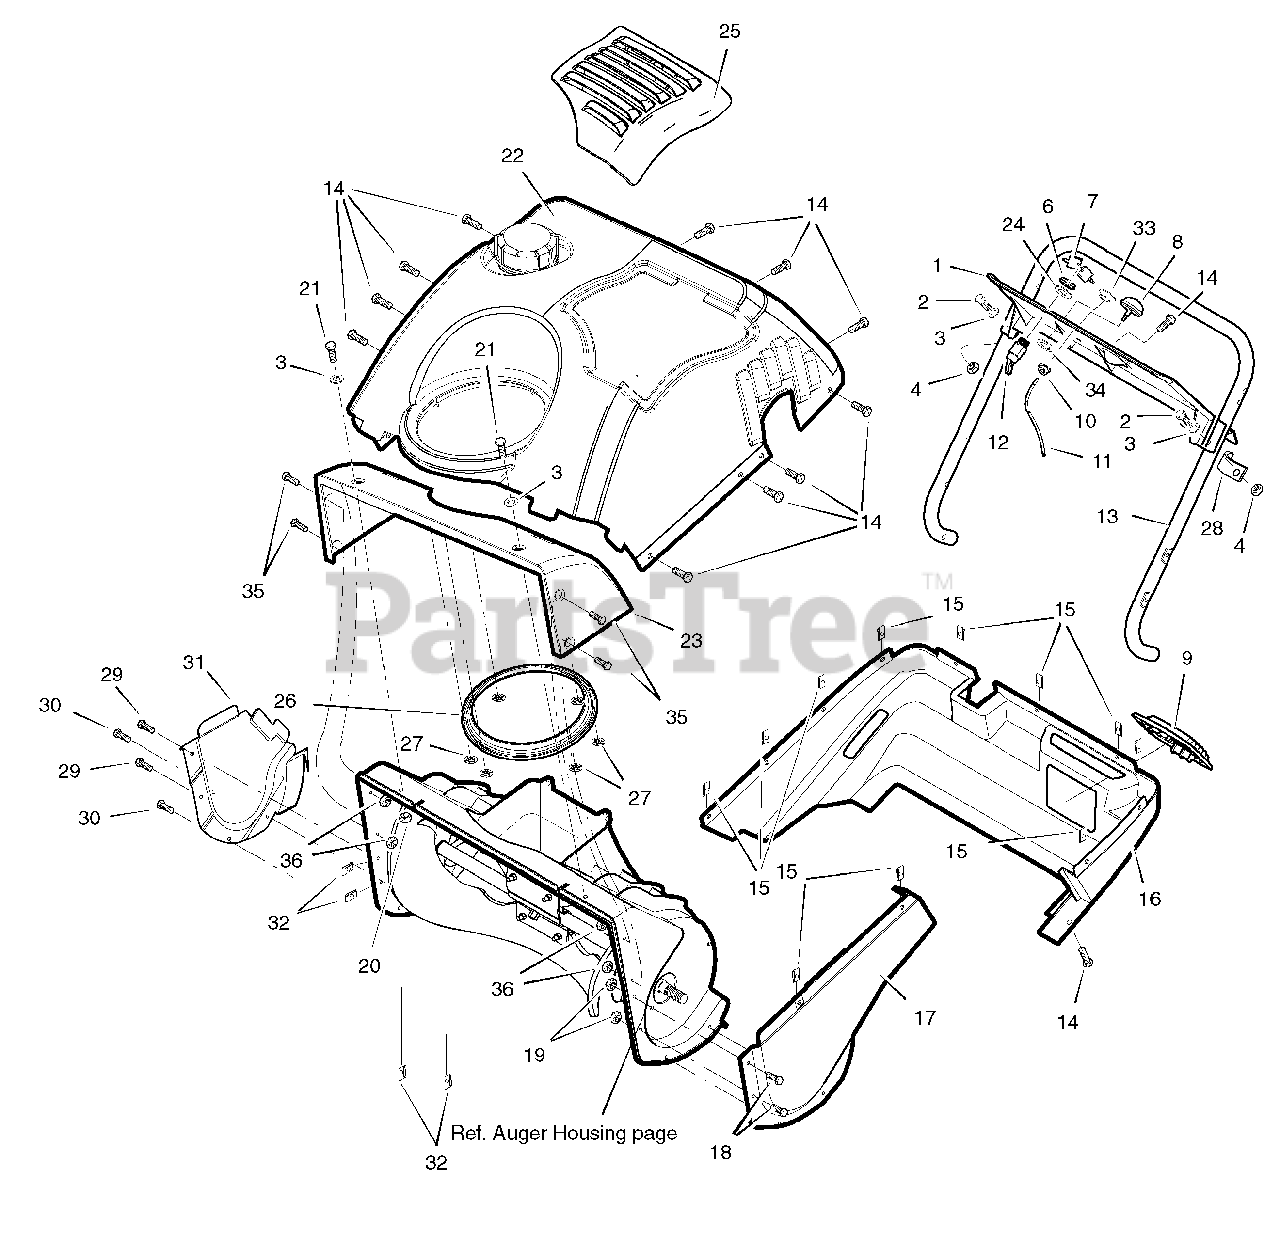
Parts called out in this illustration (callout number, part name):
1	PANEL, Control
2	CAPSCREW, 1/4-20 x 1-1/4
3	WASHER
4	NUT, 1/4-20
6	NUT, 5/8-32
8	BULB, Fuel Primer
9	COVER, Access
10	NUT, Keps 1/4-20
11	HOSE, Primer, 9.5"
12	SWITCH, Ignition
13	HANDLE, Lower
14	SCREW, Slotted, 1/4-14 x 3/4
15	NUT, 1/4-10
16	COVER, Bottom
17	COVER, Belt
18	SCREW, 10-24 x 1/2
19	NUT, Hex Center Lock, 10 24
20	LOCKNUT, Hex 1/4-20
21	SCREW, 1/4-20 x 9/10
23	COVER, Auger Top
25	COVER, Oil Access
26	Gasket, Chute Ring
27	NUT, Push Pal
28	CLIP, Cable
29	CAPSCREW, Hex Head, 10-24 x .72
30	CAPSCREW, Hex Head, 10-24 x .95
31	COVER, R.H. Auger Housing
32	J-NUT, 1/4-10
33	GROMMET, Rope
34	WASHER, Rope Grommet
35	CAPSCREW, Hex Washer Head, 10-24 x 1/2"
36	NUT, Hex Center Lock, 10-24
